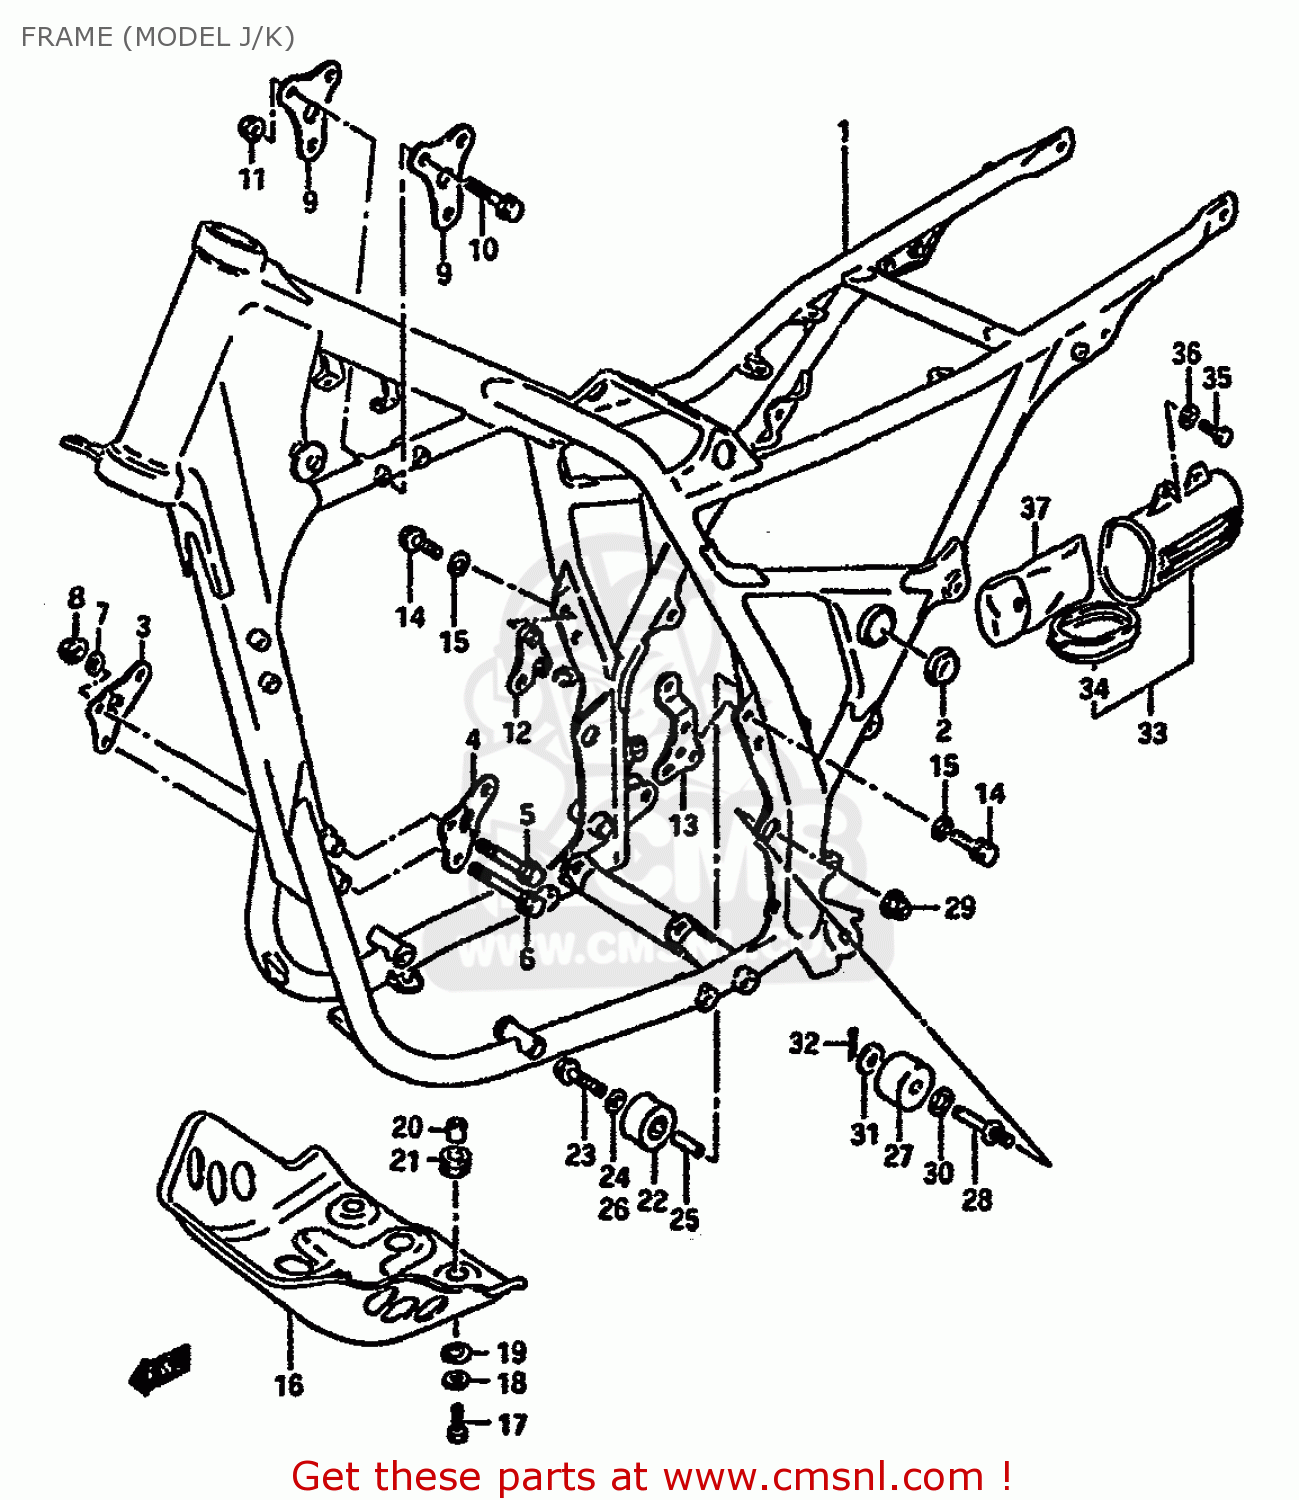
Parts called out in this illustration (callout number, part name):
1	FRAME (BLACK)
2	CAP,CUSHION LEVER
3	PLATE,ENGINE MOUNTING,FRONT
4	PLATE,ENGINE MOUNTING,FRONT
5	BOLT(8X67)
6	BOLT(8X75)
7	WASHER,LOCK
8	NUT
9	PLATE,ENGINE MOUNTING,UPPER
10	BOLT
11	NUT
12	PLATE,ENGINE MOUNTING,REAR
13	PLATE,ENGINE MOUNTING,REAR
14	BOLT
15	WASHER,LOCK
16	PROTECTOR,ENGINE
17	BOLT
18	WASHER,LOCK
19	WASHER
20	SPACER (7X9X7)
21	CUSHION
22	ROLLER,CHAIN CONTROL
23	BOLT 8X40
24	WASHER,LOCK
25	SPACER(8.6X12X25.5)
26	WASHER
27	ROLLER,CHAIN LENGTH CONTROL
28	BOLT,CHAIN LENGTH CONT LWR
29	NUT
30	WASHER
31	WASHER
32	PIN 25X20
33	HOLDER,TOOL
34	CAP,HOLDER
35	BOLT 6X16
36	WASHER (6.5X18X1.6)
37	TOOL ASSY
